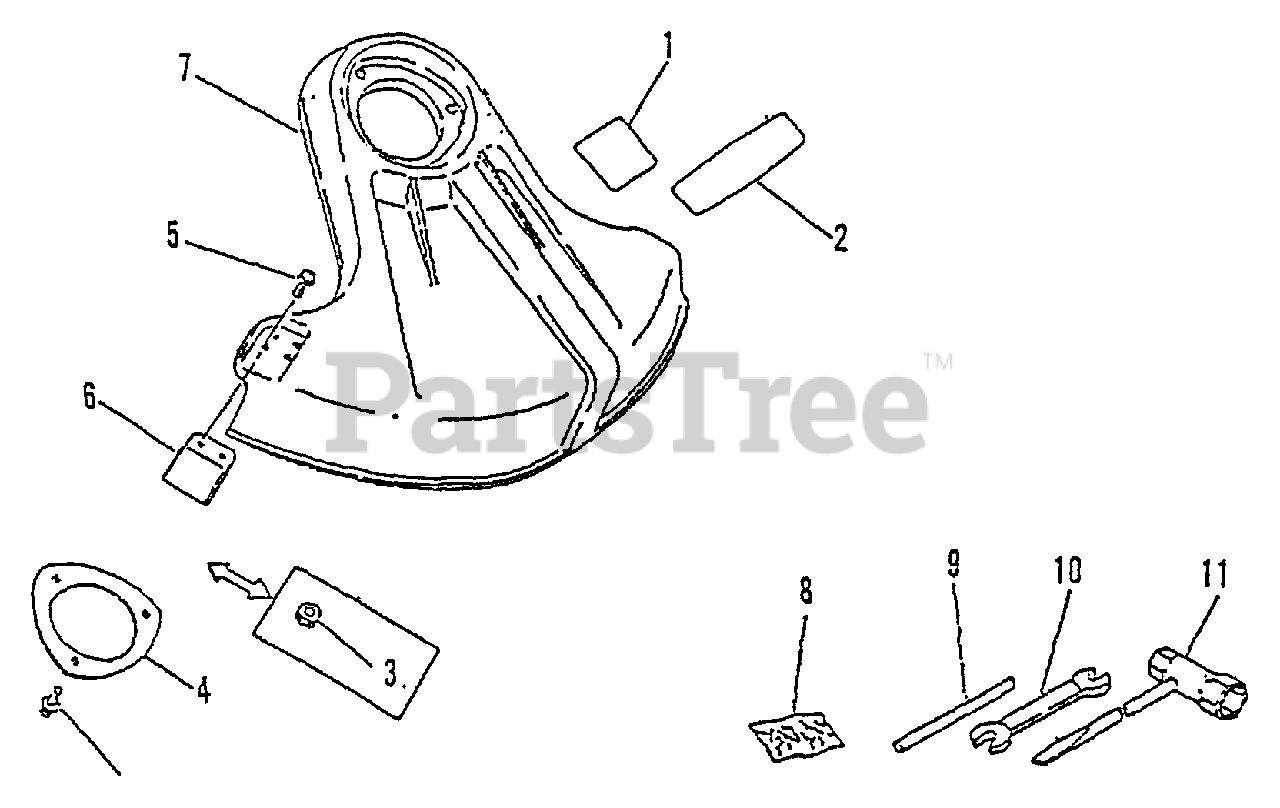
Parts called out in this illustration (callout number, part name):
1	LABEL, CAUTION
2	LABEL, ECHO
3	NUT M5
4	PLATE, SHIELD Ø49.5 MM
5	SCREW 5×16
6	CUTTER, LINE
7	DEBRIS SHIELD ASSY
8	PIN, COTTER 2×22 (PKG. OF 10)
9	TOOL, LOCKING 5×120 MM
10	SPANNER 8×10
11	T-WRENCH 17x-19 L200
